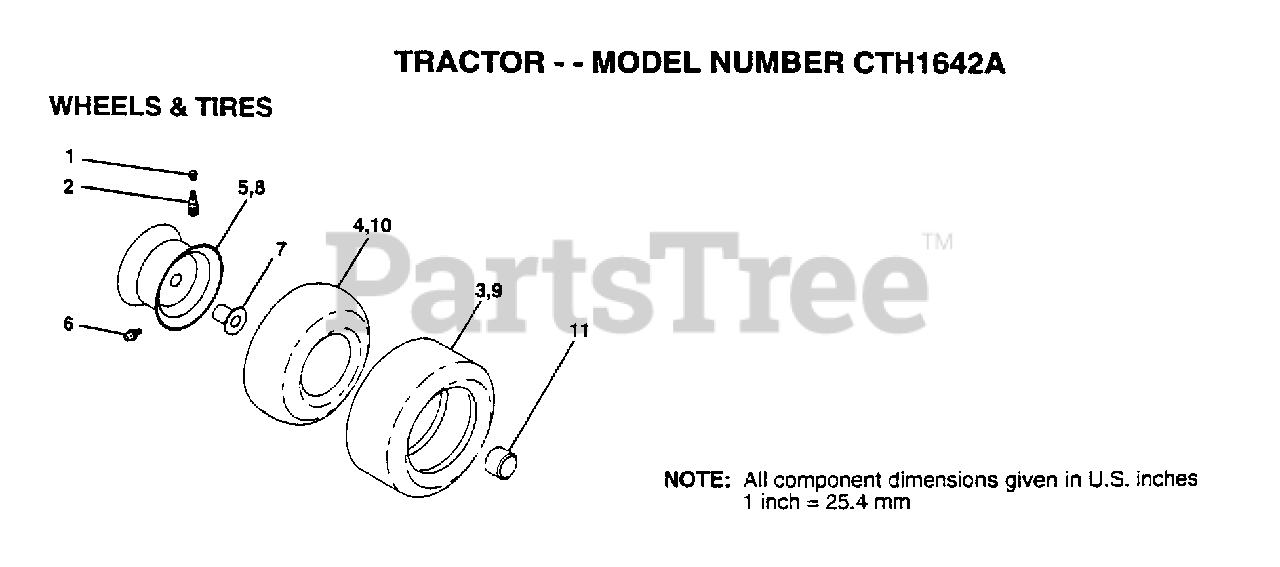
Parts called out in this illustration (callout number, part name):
1	VALVE CAP
2	VALVE STEM LT
4	TUBE.5.3/4.5/6
5	"RIM.ASM.6""FRONT"
6	FITTING LT
7	"FLANGE, BEARING"
8	"RIM.ASM.8""REAR"
10	TUBE.18X9.5-8
11	HUB CAP
